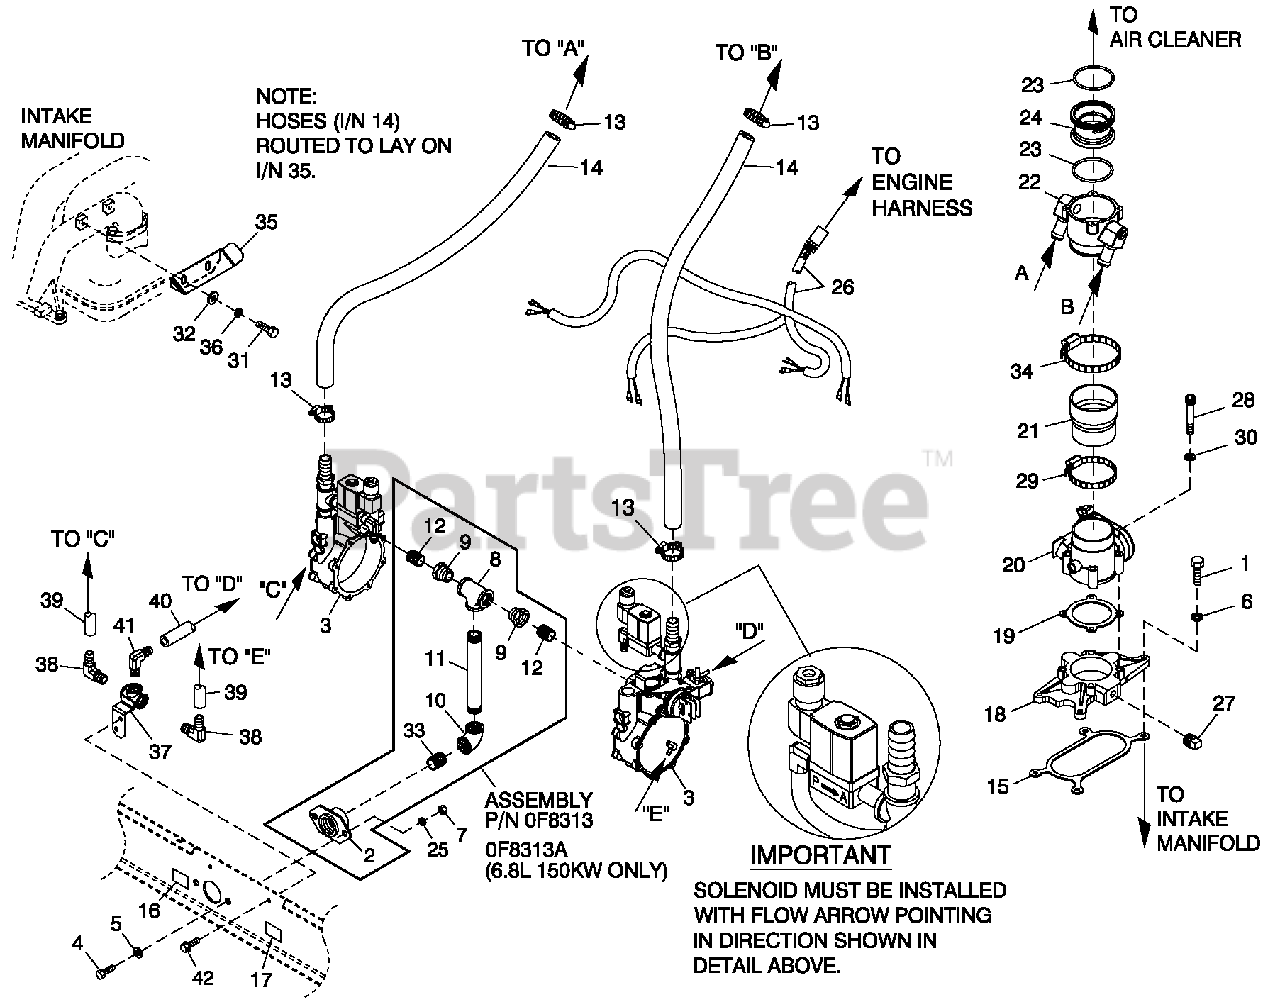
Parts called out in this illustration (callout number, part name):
1	SCREW HHC 5/16-18 X 1-1/4 G5
2	SUPPORT NAT GAS SOLENOID
3	REG 6.8L 100 KW LP CPL EMISS
4	SCREW HHC M12-1.75 X 20 G8.8
5	WASHER FLAT 1/2 ZINC
6	WASHER LOCK M8-5/16
7	NUT HEX M12-1.75 G8 YEL CHR
8	PIPE TEE 1-1/4 NPT
9	BSHG RDCRHEX1-1/4-3/4
10	ELBOW 9 0D 1-1/4 NPT
11	NIPPLE PIPE 1-1/4 NPT X 3 (100KW & 130 KW)
12	NIPPLE CLOSE 3/4X1.375
13	CLAMP HOSE #10 .56-1.06
14	HOSE 3/4 ID SAE-30R2 (45" LG)
15	GASKET ADAPTER THROT BODY
16	DECAL INLET PRESSURE
17	DECAL FUEL INLET LPG
18	ASSY,ADAPTER,THROTTLE BODY
19	GASKET GOVERNOR ACTUATOR
20	ACTUATOR BOSCH 60 GOVERNOR
21	REDUCER 3.0" TO 2.75" TURBO
22	MIXER 40/60MM ACTUATOR ASSY
23	O-RING 2-3/4X3/32X2-15/16
24	VENTURI THROTTLE 42MM (6.8L 100 KW)
25	WASHER LOCK 1/2
26	HARNESS, FUEL JUMPER DUAL REG
27	PLUG STD PIPE 1/4 STEEL SQ HD
28	SCREW SHC M6-1.0 X 50 C8.8
29	CLAMP HOSE #44 2.31-3.25
30	WASHER LOCK M6-1/4
31	SCREW HHC M6-1.0X 20 G8.8
32	WASHER FLAT M6
33	NIPPLE CLOSE 1.25 NPT X 1.625
34	CLAMP HOSE #52 2.81-3.75
35	BRACKET, HOSE RISER
36	WASHER LOCK M6-1/4
37	PIPE TEE W/ BRAC KET WELDED
38	BARBED EL 90 3/16X1/8
39	HOSE VACUUM 5/32 (12.0"LG)
40	HOSE VACUUM 5/32 (10.5"LG)
41	BARBED EL W/VENT (.052")
42	SCREW THF M6-1 X 16 N WA Z/JS
